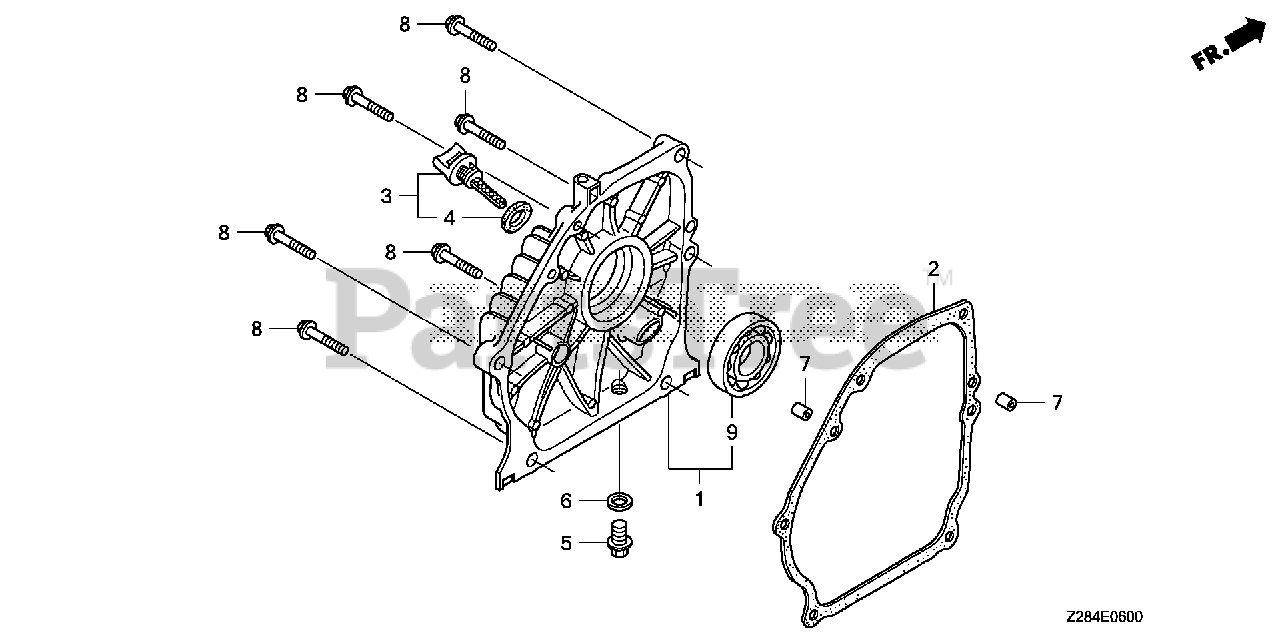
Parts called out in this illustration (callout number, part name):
1	COVER, CRANKCASE
2	GASKET, CASE COVER (NON-ASBESTOS)
3	CAP ASSY., OIL FILLER
4	GASKET, OIL FILLER CAP
5	BOLT, DRAIN PLUG
6	WASHER, DRAIN PLUG (10.2MM)
7	PIN A, DOWEL (8X14)
8	BOLT, FLANGE (8X32)
9	BEARING, RADIAL BALL (6205)
